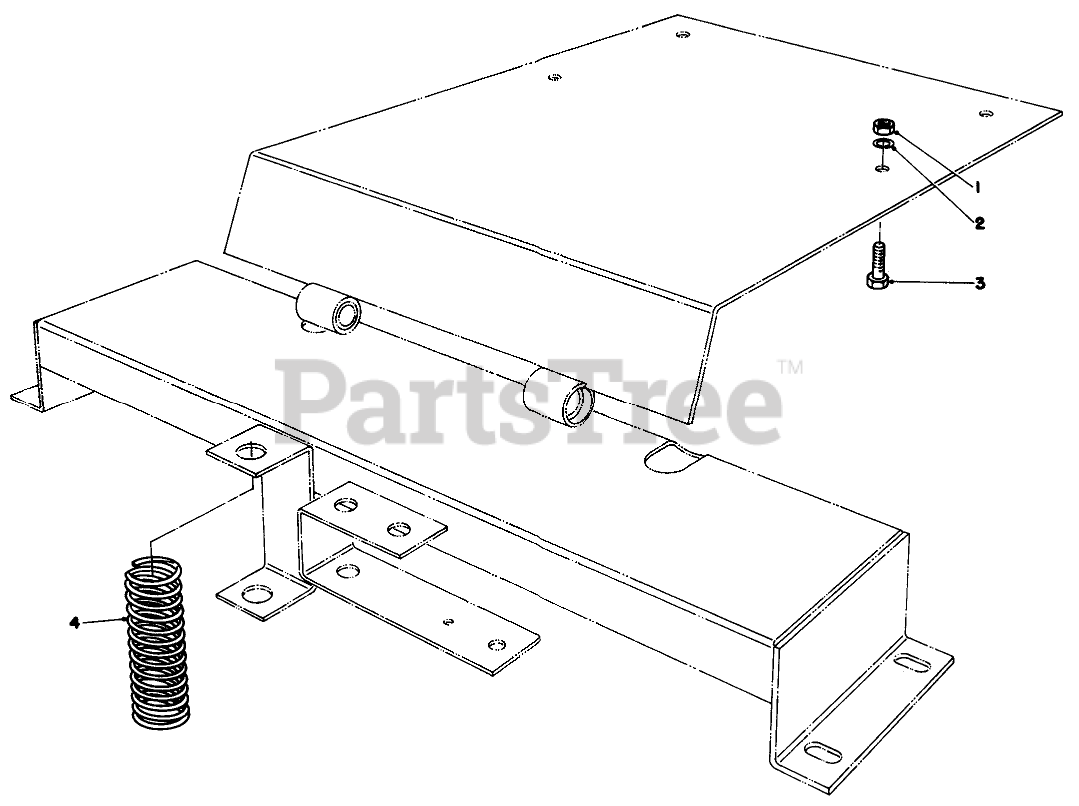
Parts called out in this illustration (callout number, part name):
1	NUT-HEX
2	WASHER-LOCK/SP
3	SCREW-HH
4	COMP SPRING
